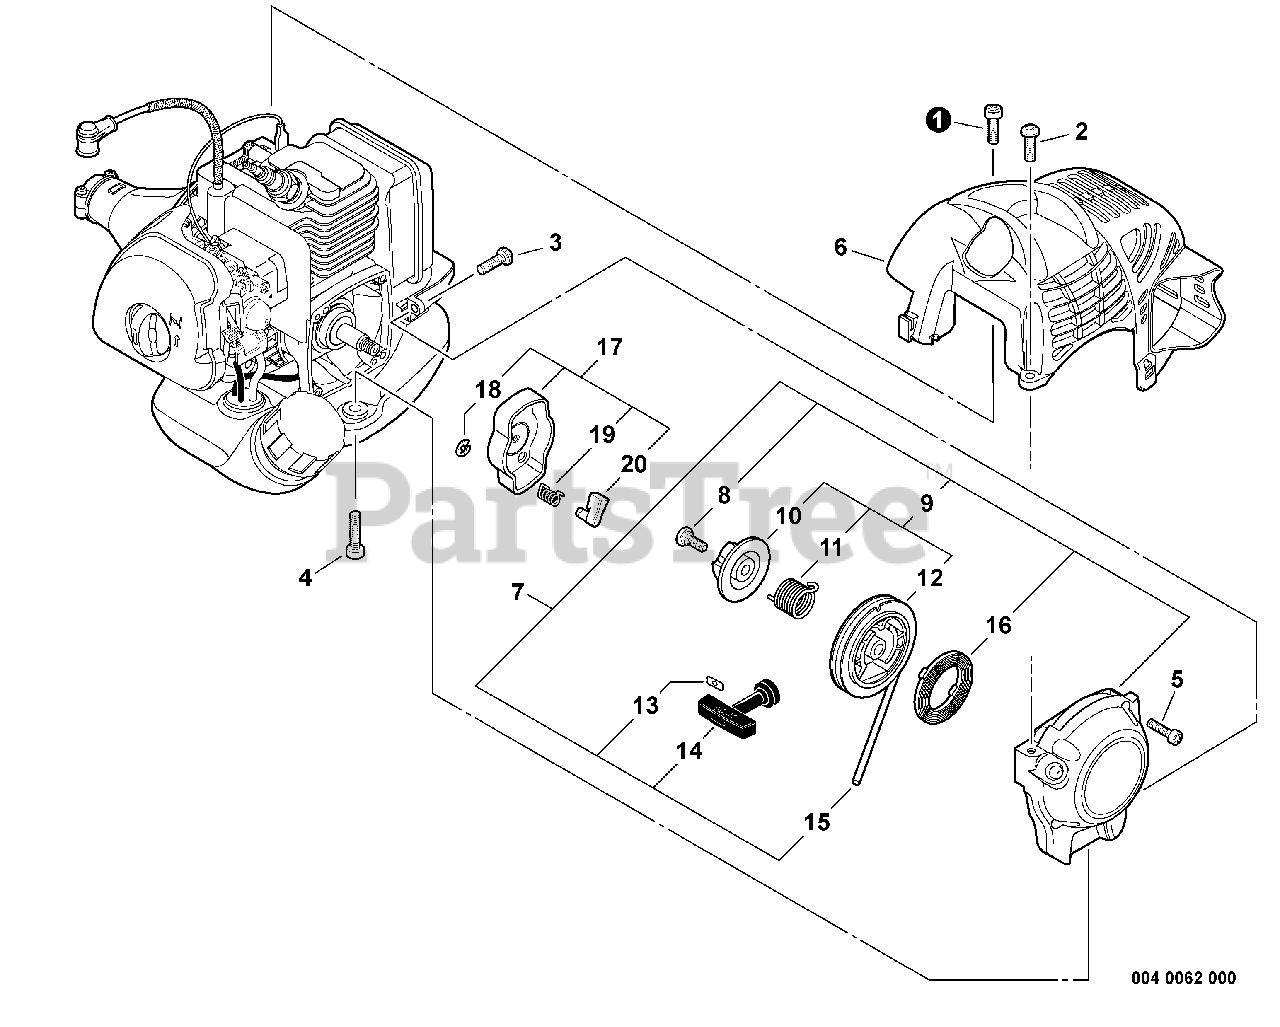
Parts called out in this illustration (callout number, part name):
1	SCREW - 5X16
2	SCREW - 5X16
3	SCREW - 5X16
4	SCREW - 5X25
5	SCREW - 4X16
6	COVER, ENGINE
7	STARTER ASSY
8	SCREW
9	ROPE REEL KIT
10	PLATE, CAM
11	SPRING, DAMPER
12	REEL, ROPE
13	RETAINER, ROPE
14	GRIP, STARTER
15	ROPE, STARTER - 3X700
16	SPRING, REWIND
17	STARTER PAWL ASSY
18	RING, RETAINING - 4
19	SPRING, RETURN
20	PAWL, STARTER
